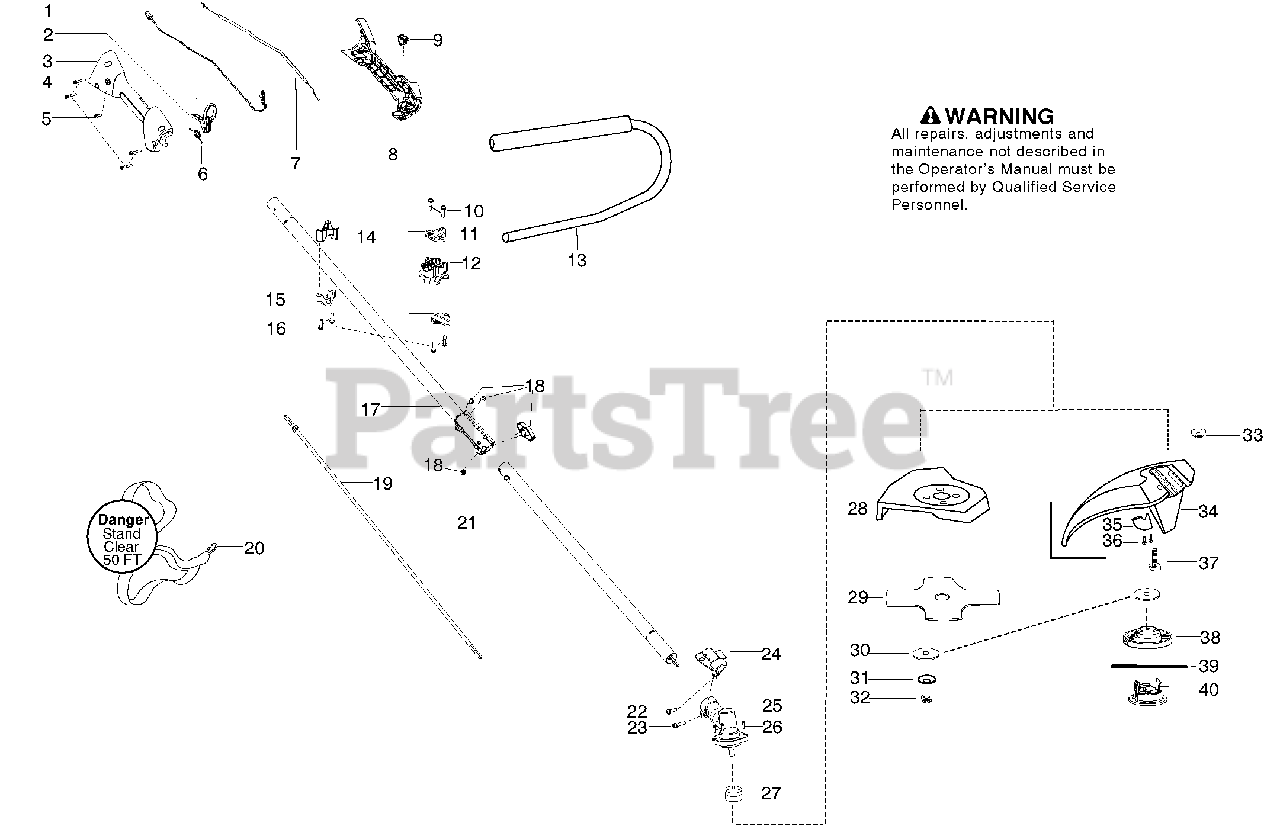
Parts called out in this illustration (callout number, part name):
1	Assy-Switch Wire
2	Kit - Trigger
3	Housing -Throttle (RH)
4	Screw M4
5	Screw 10-14 x 1/2
6	Spring-Trigger
7	Cable - Throttle
8	Housing-Throttle (LH)
9	Kit-Switch
10	Screw 10-14 x 13/16
11	Clamp - Bracket
12	Clamp - Handlebar
13	Kit - Handlebar
14	Clamp - Upper Harness
15	Clamp - Lower Harness
16	Screw - 10-14 x .095
17	Kit - Upper Drive Shaft
18	Kit - Knob / Screw
19	Flexshaft - lower
20	Shoulder Strap
21	Kit - Lower Drive Shaft
22	Screw - 8-16 x .593
23	Screw - 12-24 x .960
24	Bracket - Shield SST
25	Assy - Gearbox 1" Brushcutter
26	Screw 10-24
27	Dust cup
28	Kit - Metal Blade Shield
29	Assy. - Blade
31	Washer - Belleville
32	Nut - Flange (L.H.)
33	Wingnut 1/4-20
34	Kit - Shield
35	Line Limiter
36	Screw - 10-14 x 3/4
37	Bolt - 1/4-20 x 1-1/4
38	Head - Fixed Line
39	Line - Accy. 12 pcs. (.115 Round)
40	Cap - Fixed Line
